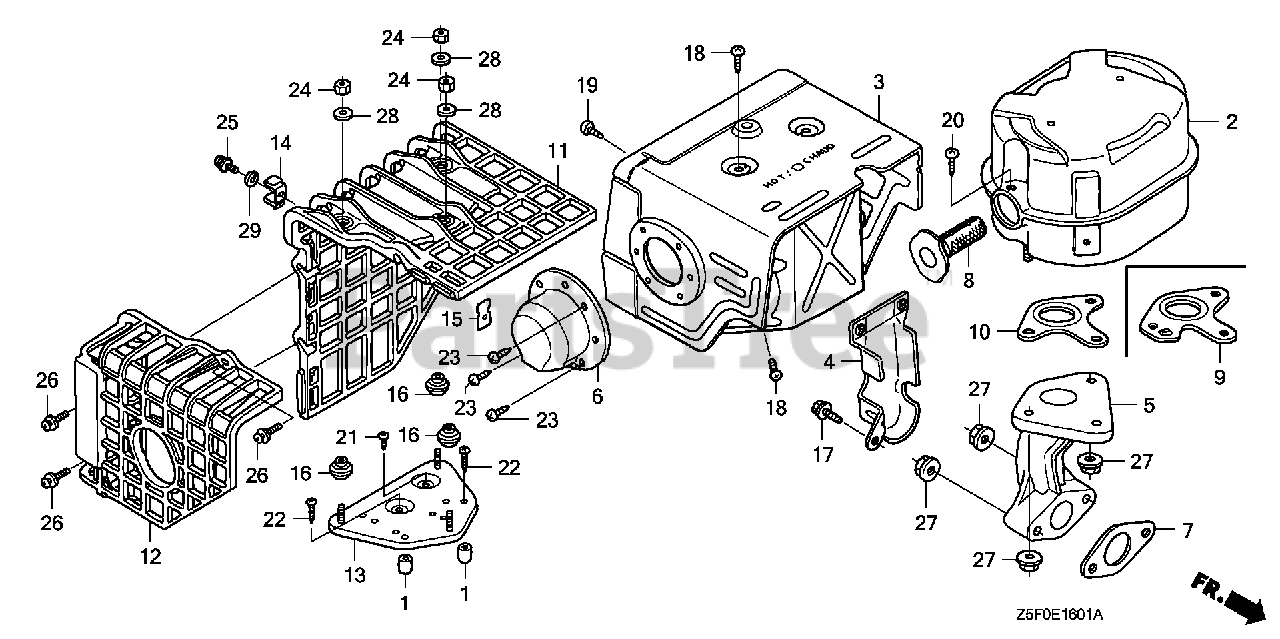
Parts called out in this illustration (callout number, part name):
2	MUFFLER
3	PROTECTOR, MUFFLER (STD)
4	PROTECTOR, EX. PIPE
6	CAP, MUFFLER
7	GASKET, EX. PIPE Use up to Engine SN 2949254.
7	GASKET, EX. PIPE (WACKER)
8	ARRESTER, SPARK
9	GASKET, MUFFLER (ARRESTER)
9	GASKET, MUFFLER (ARRESTER)(THAI LEAKLESS)
17	BOLT, FLANGE (6X12) (CT200)
18	SCREW, TAPPING (5X8)
19	SCREW, TAPPING (5X8)
20	SCREW, TAPPING (5X8)
23	SCREW, TAPPING (4X6) (TO INSTALL OPTIONAL SPARK ARRESTER)
27	NUT, FLANGE (8MM)
